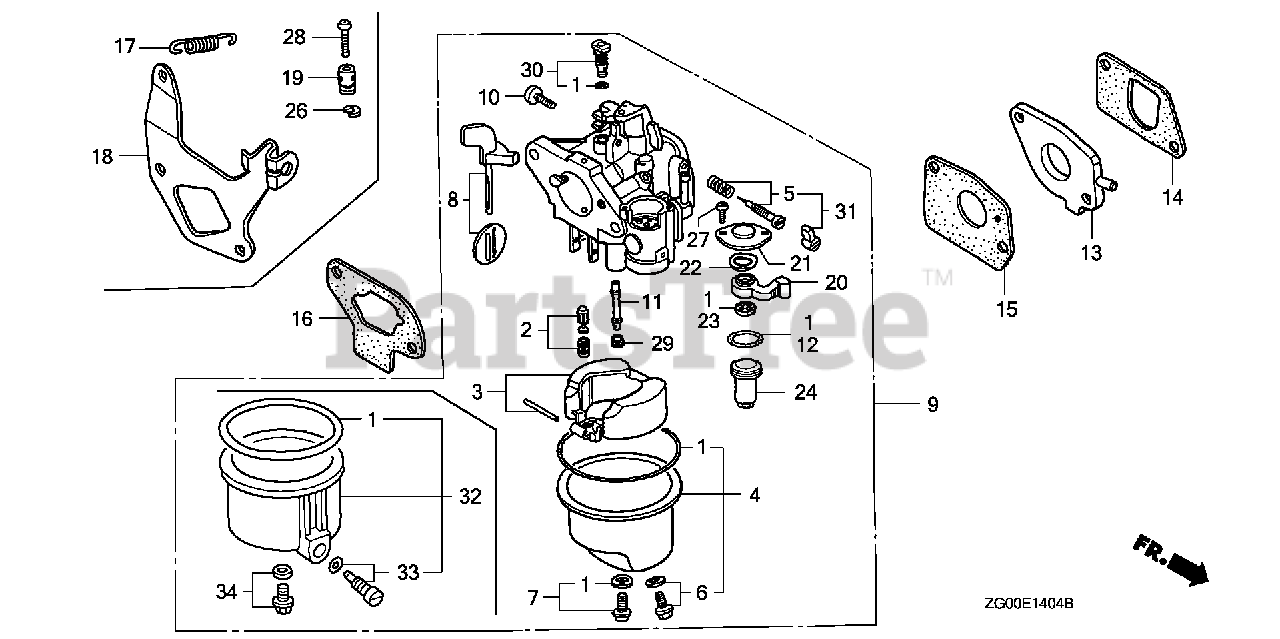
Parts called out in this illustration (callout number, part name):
2	VALVE SET, FLOAT
4	CHAMBER SET, FLOAT (CARBURETOR NO.)
6	SCREW SET, DRAIN (CARBURETOR NO.)
7	SCREW SET (CARBURETOR NO.)
10	SCREW, THROTTLE STOP
11	NOZZLE, MAIN (CARBURETOR NO.)
13	INSULATOR, CARBURETOR
14	GASKET, INSULATOR
15	GASKET, CARBURETOR
16	GASKET, AIR CLEANER
20	LEVER, VALVE (CARBURETOR NO.)
21	PLATE, LEVER SETTING (CARBURETOR NO.)
22	SPRING, VALVE LEVER
23	GASKET, VALVE
27	SCREW, PAN (3X6)
29	JET, MAIN (#50)
29	JET, MAIN (#52)
29	JET, MAIN (#55) (CARBURETOR NO.)
30	JET SET, PILOT (#35) (CARBURETOR NO.)
31	SCREW SET (CARBURETOR NO.)
